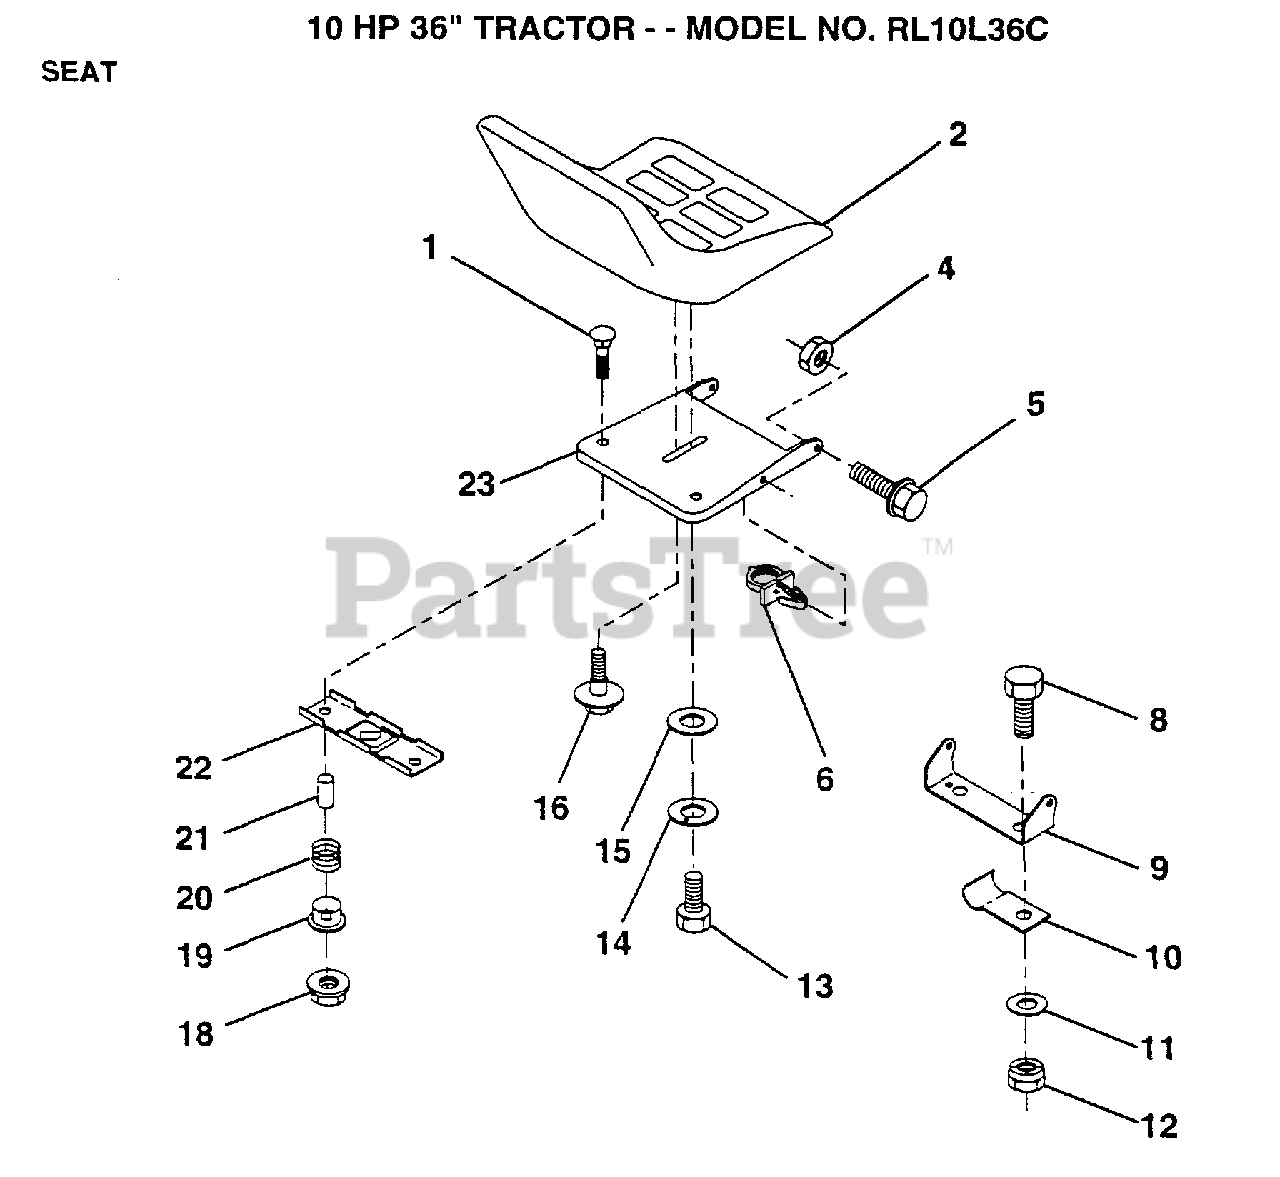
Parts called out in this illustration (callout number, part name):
4	NUT
5	BOLT.SHLD.5/16-18
6	CLIP PUSH - IN
8	BOLT
9	BRACKET PVT SEAT
10	"CLIP,INSULATOR"
11	WASHER
12	NUT
13	BOLT
14	LOCKWASHER
15	WASHER
16	"BOLT,SHOULDER"
19	BUSHING
20	SPRING
21	SPLIT SPACER
22	BRKT SWITCH
